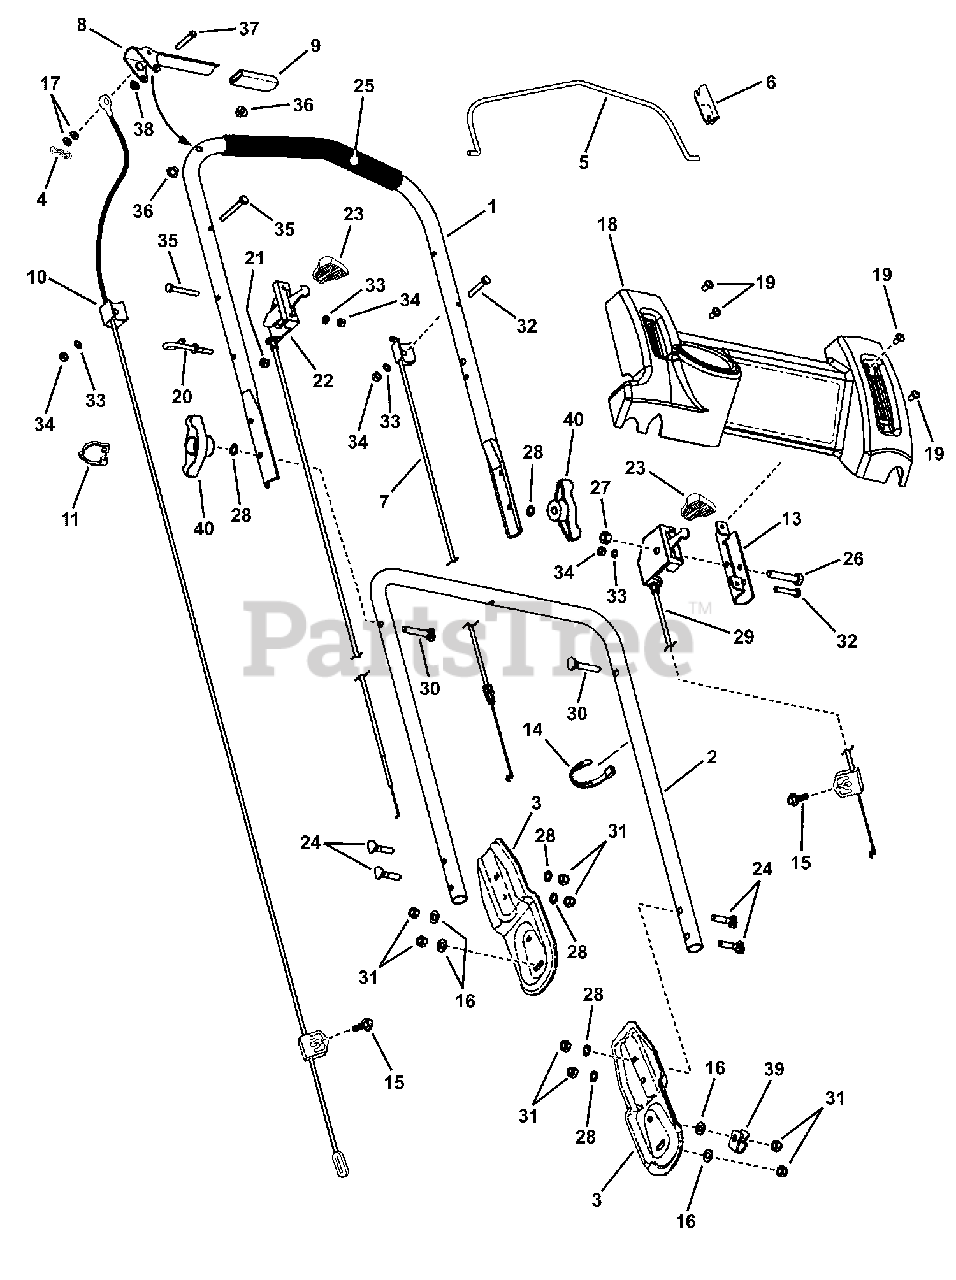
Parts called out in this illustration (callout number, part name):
1	HANDLE, Upper
2	HANDLE, Middle
3	BRACKET, Handle
4	COTTER PIN, Bow Tie Locking
5	BAIL, OPC Control
6	CLIP, Zone Control
7	* CABLE, Zone Control (53.98")
7	* CABLE, Zone Control (OPC) DOV Engine (53.73")
8	WELDMENT, Handle Clutch
9	GRIP, International Symbol
10	CABLE, Clutch (Adjustable)
11	CLAMP, 7/8" Double Cable
13	BRACKET, Shift
14	WIRE TIE, 1.29" Long Black
15	SCREW, #10-24 x 5/8" Slotted Hex Washer Head Self-Tap
16	WASHER, 11/32" Flat
17	WASHER, 7/32" Flat
18	CONTROL PANEL (w/o El. Switch Hole)
19	SCREW, 1/4-20 x 1/2" Pan Head Self-Tap (Torx)
20	ROPE GUIDE (1/4-20 threads)
21	NUT, 1/4-20 Hex Nyloc
22	* THROTTLE CONTROL, 7.0 HP B&S (48.5")
22	* THROTTLE CONTROL, 6.75 HP B&S DOV (48.0")
23	THROTTLE KNOB
24	BOLT, 5/16-18 x 1-1/2" Curved Head Carriage
25	FOAM GRIP, 18.75"
26	SCREW, 3/8-16 x 2" Hex Head Self-Tap
27	NUT, 3/8-16 Hex Center Lock
28	WASHER, 5/16" Internal Tooth Lock
29	* CONTROL, Speed Select
30	SCREW, 5/16-18 x 2" Square Neck Curved Head
31	NUT, 5/16-18 Hex Nyloc
32	SCREW, 1/4-20 x 1-1/2" Hex Head Cap GR 5
33	WASHER, 1/4" Internal Tooth Lock
34	NUT, 1/4-20 Hex
35	SCREW, 1/4-20 x 2" Hex Head Cap GR 5
36	BUSHING, .27 x .35 x .4 Flange
37	PIN, 1/4 x 1-1/2"
38	PUSHNUT, 1/4"
39	CLAMP, Double Tube
40	KNOB, 5/16-18 Wing (Black)
